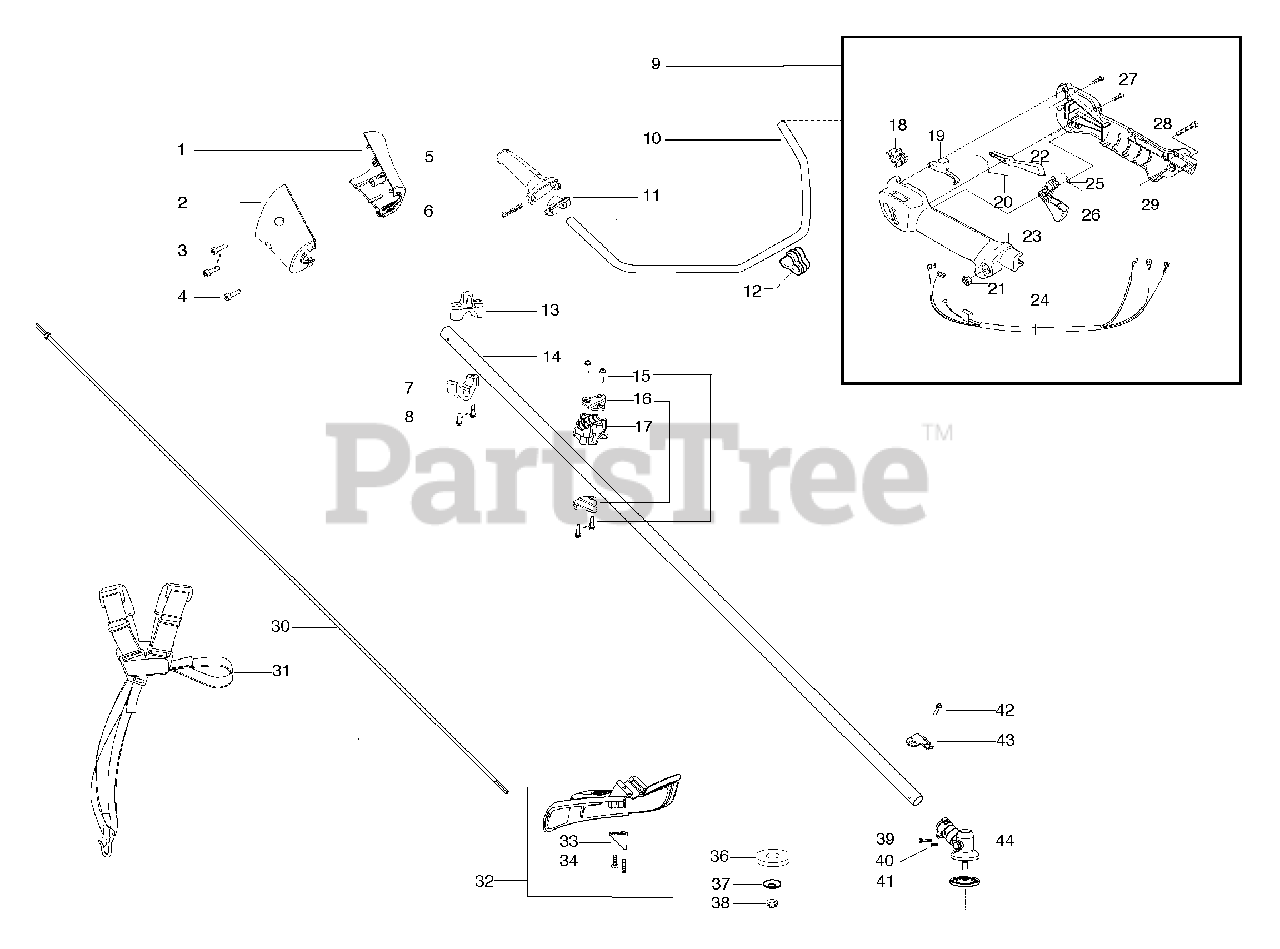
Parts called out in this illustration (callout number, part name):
1	Nose Cone - LH
2	Nose Cone - RH
5	Handle-Assist
7	Clamp-Harness (lower)
9	Assy-Throttle Housing
11	Cover-Assist Handle
12	Clip-Handlebar
13	Clamp-Harness (upper)
14	Kit-Driveshaft
16	Clamp - Bracket
17	Clamp 1" Handlebar
18	Kit-Switch
19	Lockout-Starter Throttle
20	Spring - Lockout
22	Lockout - Throttle
23	Housing - Throttle -LH
24	Assy - Cable Wire
25	Spring - Trigger
26	Trigger - Throttle
28	Screw
29	Housing-Throttle - RH
31	Harness w/o warning
32	Kit-Shield
33	Limiter - Line
36	Cup-Support
37	Support - Flange
38	Locknut - Blade
41	Assy - Dustcup
43	Bracket - Shield
44	Assy - Gearbox
